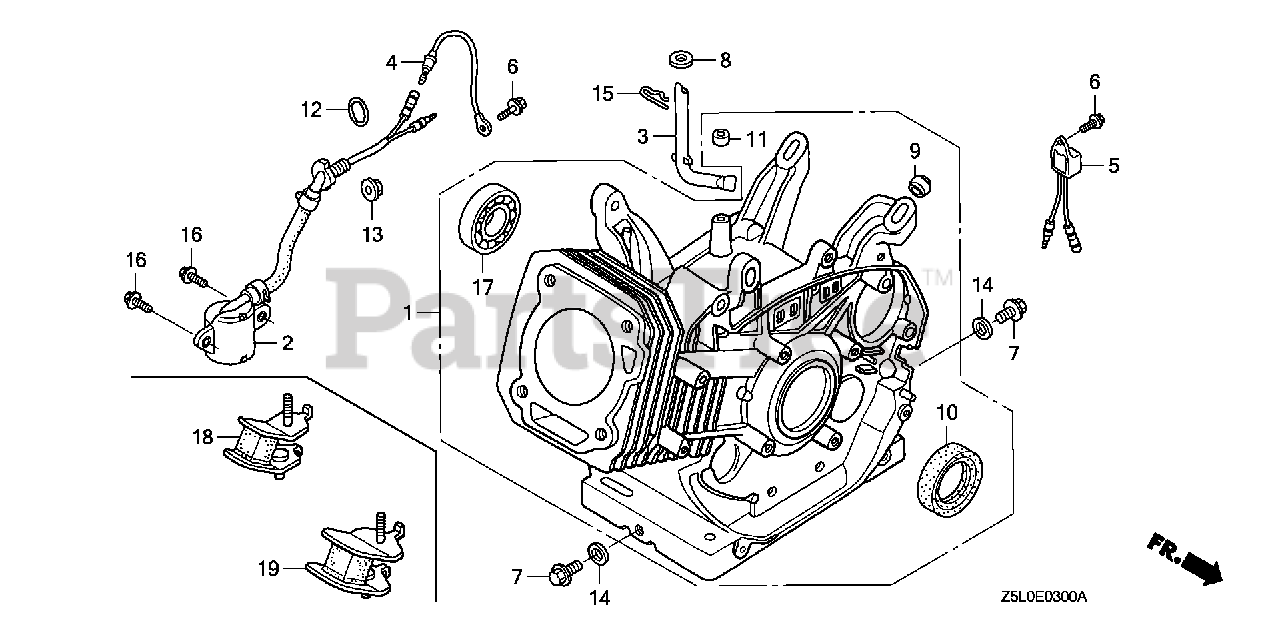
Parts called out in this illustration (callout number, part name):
1	CYLINDER ASSY. (SELF STARTER+ALERT)
2	SWITCH ASSY., OIL LEVEL
3	SHAFT, GOVERNOR ARM
7	BOLT, DRAIN PLUG
8	WASHER (8.2X17X0.8)
10	OIL SEAL (35X52X8)
10	OIL SEAL (35X52X8) (NOK)
11	OIL SEAL (8X14X5)
12	O-RING (14MM) (ARAI) Use up to Engine SN 2949254.
12	O-RING (14MM) (NOK)
13	NUT, FLANGE (10MM)
14	WASHER, DRAIN PLUG (12MM)
15	PIN, LOCK (10MM)
16	BOLT, FLANGE (6X12) Use up to Engine SN 1543277.
17	BEARING, RADIAL BALL (6202)
